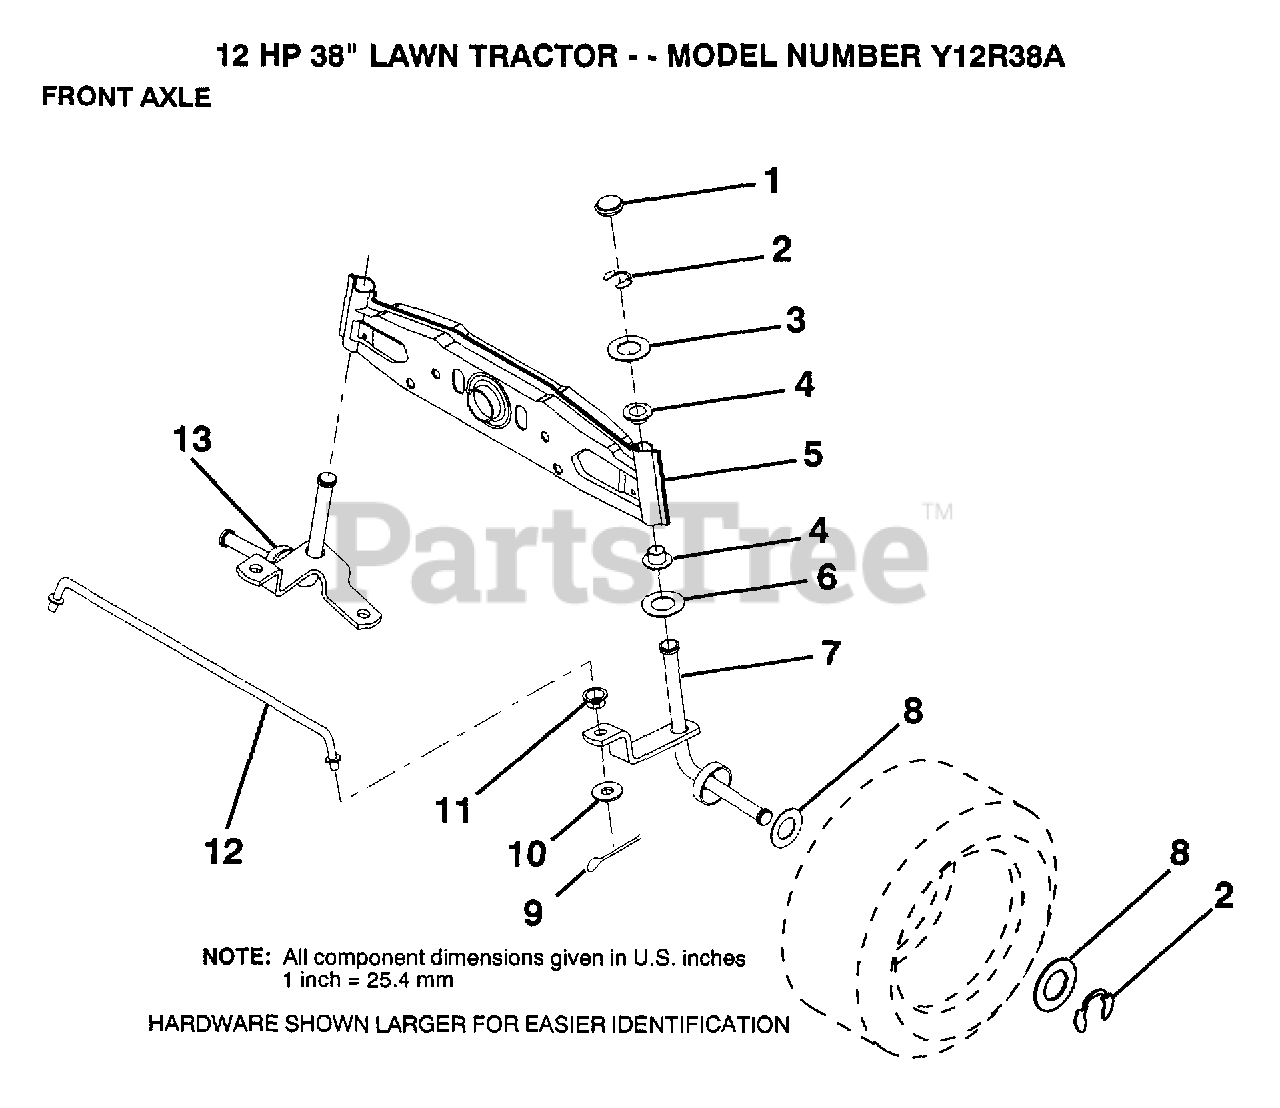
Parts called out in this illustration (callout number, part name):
1	CAP
2	RING
3	WASHER
4	NYLINER
5	AXLE FRONT
6	WASHER .T
7	SPINDLE RH
8	WASHER
9	COTTER PIN
10	WASHER
11	BUSHING.DRAGLINK
12	ROD TIE
13	SPINDLE LH
